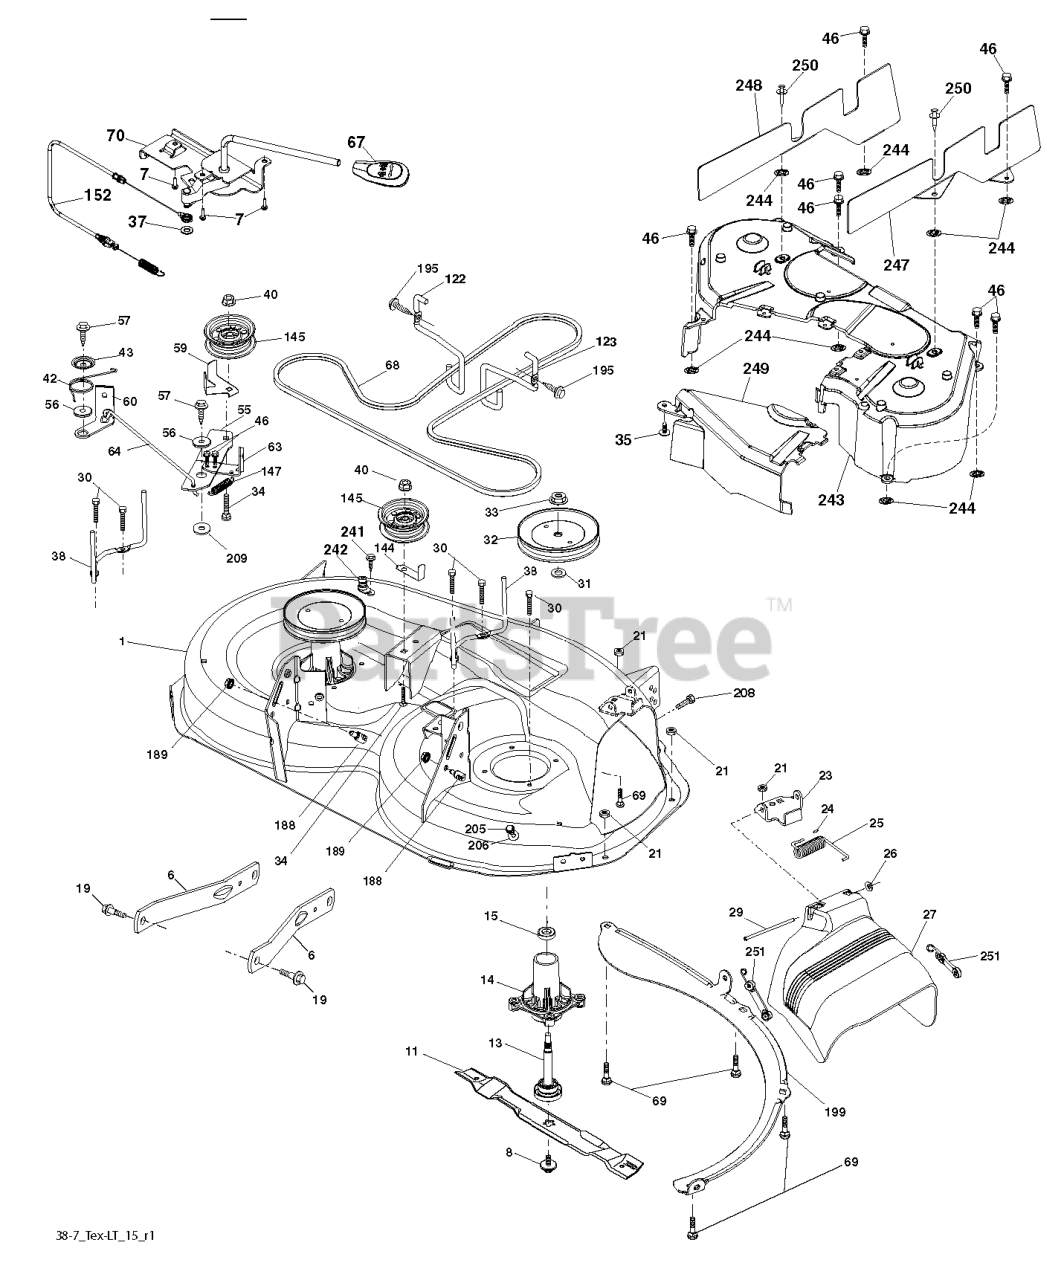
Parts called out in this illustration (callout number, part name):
1	HOUSING
6	ARM.SUSPENSION.MOWER.R
7	SCREW.#10 X 0.750.BOS
8	BOLT.WASHER.ASM.7/16-2
11	BLADE 38" PREMIUM
13	SHAFT.ASM.MDRL.N/GREASE.38
14	RP.HOUSING.MANDREL.4PT.
19	BOLT.SHOULDER
21	LOCKNUT
23	BRKT.DEFLECTOR.38"2005+
24	CAP-SLEEVE LT
25	SPRING.TORSION.DEFLECT
26	NUT PUSH M
27	SHIELD ASM.DFLCTR MWR.38-7"BLK
29	ROD.HINGE
30	SCREW, WASHER HEAD
31	WASHER.SPACER.MANDREL
32	PULLEY.MANDREL.5.0.PD.38"
33	NUT.FLANGE.LOCK.TOP
34	BOLT.3/8-16X1.50
35	FASTENER.XMAS.TREE
37	WASHER
38	KEEPER BELT LH MANDREL
40	NUT LOCK FLG 3/8-16 UNC
42	SRPING.TORSION.RETAINE
43	SPRING.TORSION.BRAKE
46	SCREW.1/4-20X5/8
56	SPACER.RETAINER
57	SCREW 3/8-16X1
59	GUARD, BELT
60	ARM BRAKE MOWER RH 38"
63	RP ARM.BRAKE.MOWER.38"LH.TEX
64	LINK BRAKE
67	HANDLE.CLUTCH.CABLE.LT
69	BOLT
70	CLUTCH.ASM.MANUAL.LT.PRED
122	KEEPER BELT ENGINE LH
123	KEEPER BELT RH
144	KEEPER BELT
145	PULLEY.IDLER.48"PRIMARY
147	SPRING RETURN
152	CLUTCH CABLE
188	STUD.FASTNER.W/ANTI-ROTATE
189	NUT LOCK HEX FLANGE 5/16-18
195	SCREW, 3/8-16X3/4
199	BAFFLE.VORTEX.FRONT.38"
205	SCREW
208	SCREW 3/8-16X1/2
209	WASHER 12/32X2X10GA
241	SCREW.TT.#10-32X.5.3/8.FLANGE
242	PORT.WASHOUT
243	COVER DECK 38-7
244	PALNUT 1/4
247	SHIELD DECK RIGHT
248	SHIELD DECK LEFT
249	COVER CABLE CLUTCH
250	SCREW
251	ELASTIC STRAP KIT
